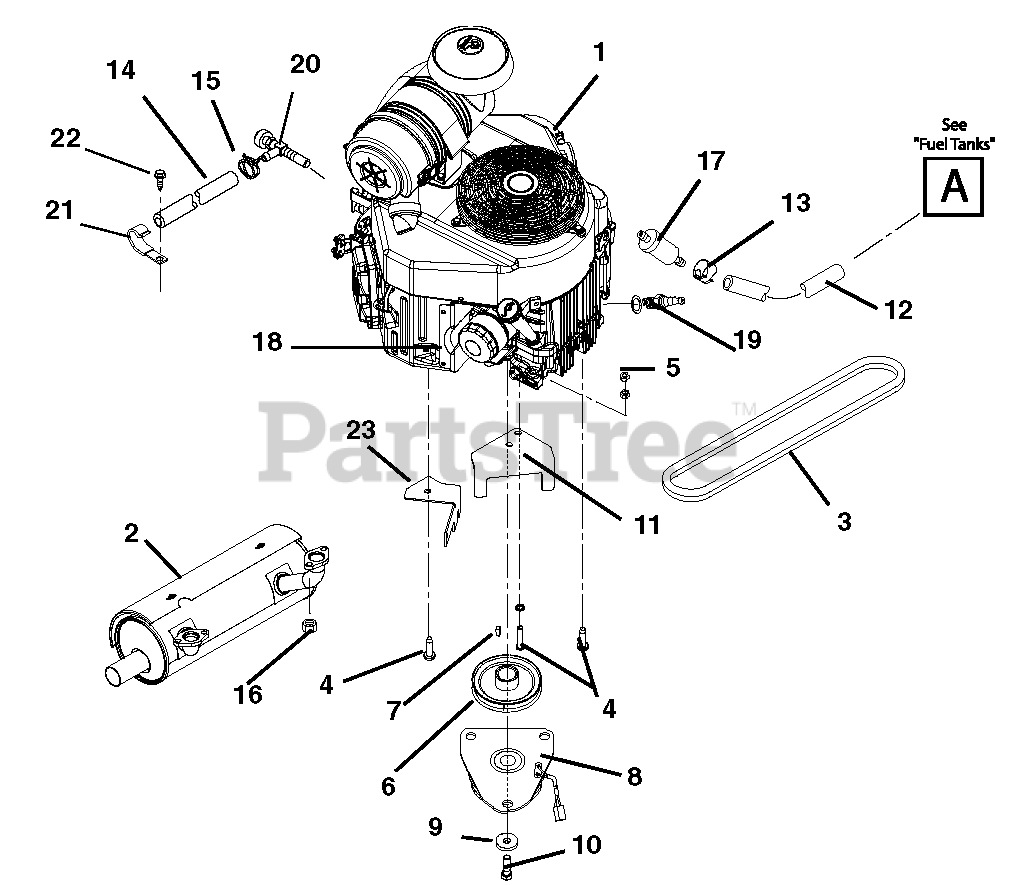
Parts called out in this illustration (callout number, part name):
1	Engine, Kawasaki Fixed 481
2	Muffler, Kawasaki
3	V-Belt, 53.7 Inches
4	Screw, Tapping Hex Washer Head .38-16 x 1.50
5	Nut, Locking Nylon Flange .31-18
6	Sheave-4.30 x 1.127 x 1.30 Engine
7	Key, Square .25 x .625 x .25 SAE 8630 OR SAE 1035
8	Clutch, Ogura
9	Washer, Flat Steel .463 x 1.375 x .250
10	Bolt, Hex .44-20 x 1.50 Grade 5 EP80
11	Anchor, Ogura Clutch
12	Hose, Gas Line .25" I.D.
13	Hose, Clamp
14	Hose, .50 x 6.00
15	Clamp, .88 Diameter Hose
16	Nut, Top Lock M8-1.25
17	Fuel Filter, Kawasaki
18	Oil Filter, Kawasaki
19	Spark Plug, Kawasaki
20	Drain, .50 Oil
22	Screw, Tapping .312-12 x .375 Hex Washer Head
23	Guard, Clutch Wire
